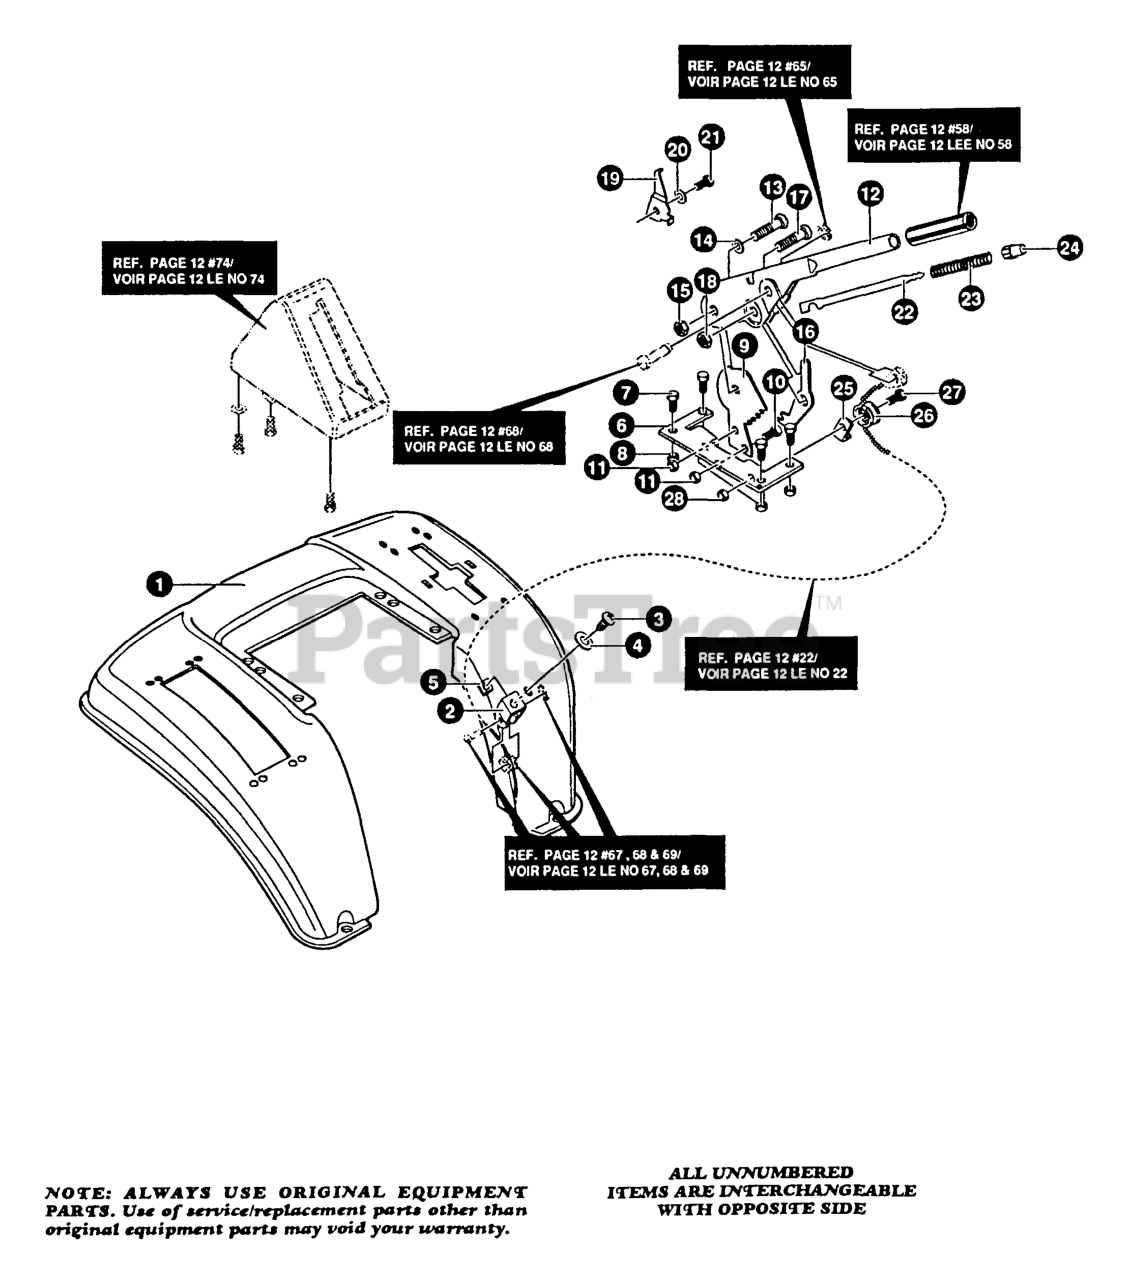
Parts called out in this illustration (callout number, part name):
4	WASHER
6	BRACKET
7	SCREW
9	QUADRANT
10	SCREW
12	HANDLE
14	WASHER
16	PAWL, SQUARE
19	POINTER
20	WASHER
21	SCREW
22	ROD, ACTUATOR
25	CABLE, BRKT
